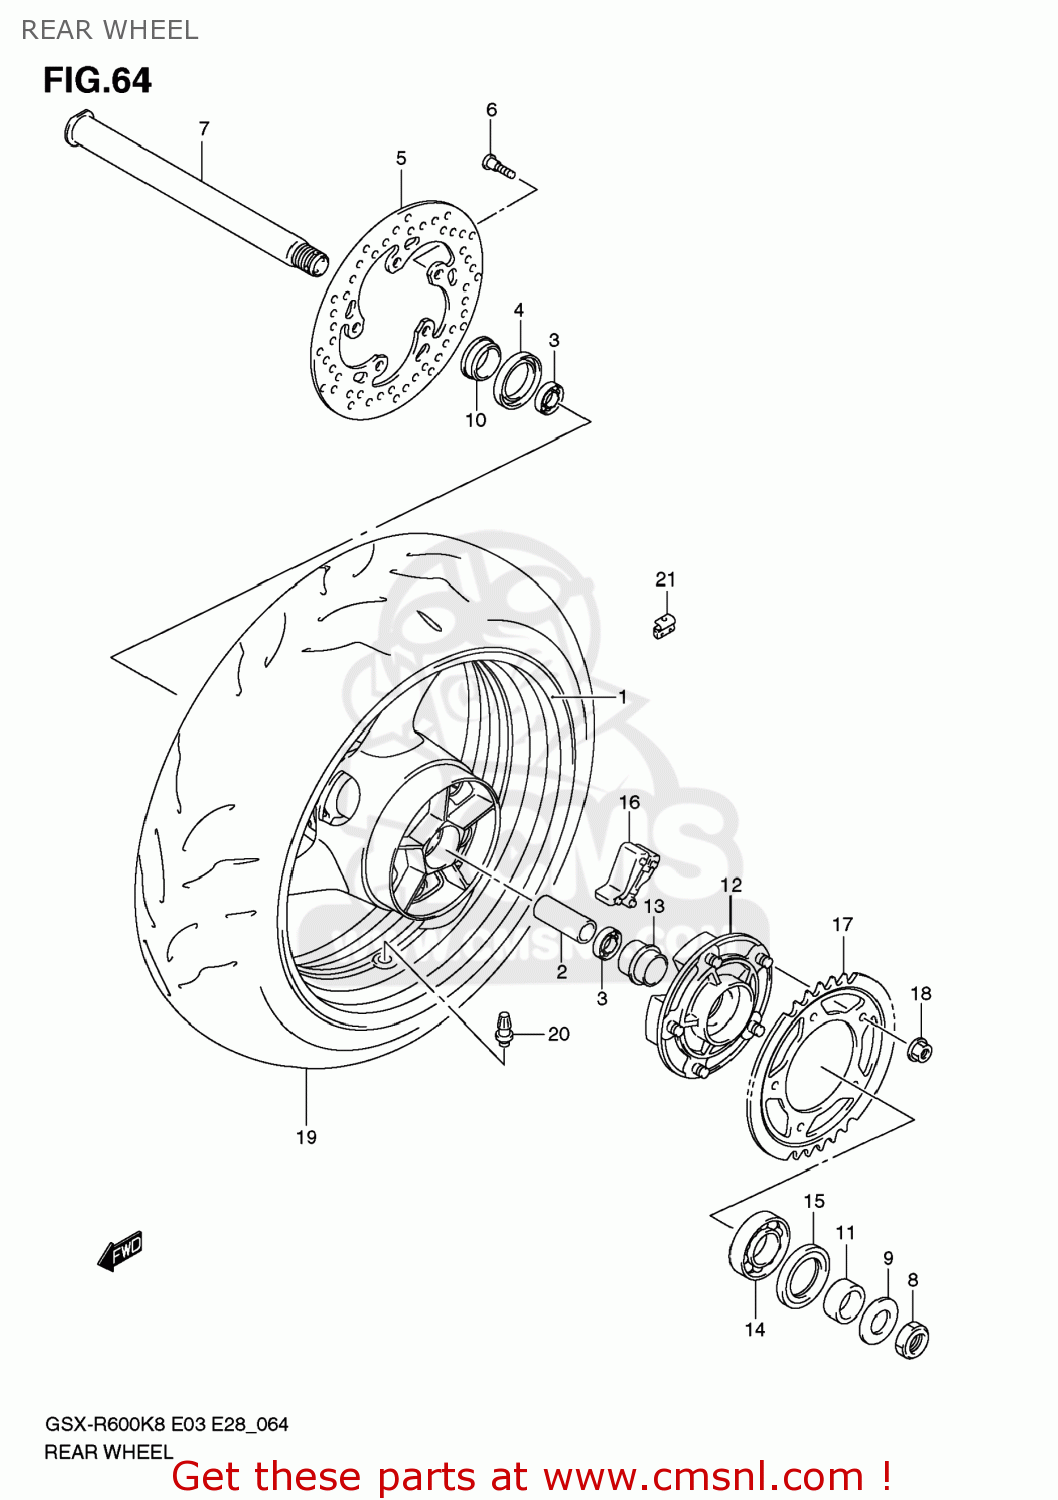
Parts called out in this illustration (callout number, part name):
1	WHEEL,RR(17M/CXMT5.50)
2	SPACER,RR WHEEL BEARING
3	BEARING(28X52X12)
4	SEAL,OIL(37X52X8)
5	DISC,RR BRAKE
6	BOLT(8X21)
7	AXLE,RR
8	NUT
9	WASHER(25.2X42X3.2)
10	SPACER,RR AXLE,R
11	SPACER,RR AXLE,L
12	DRUM,RR SPROCKET
13	RETAINER,RR SPROCKET DRUM
14	BEARING
15	SEAL,OIL(39X65X7)
16	ABSORBER,RR HUB SHOCK
17	SPROCKET,RR(43T-525)
18	NUT
19	TIRE,RR
20	VALVE ASSY,WHEEL RIM(TR412)
21	BALANCER,WHEEL(10G)
